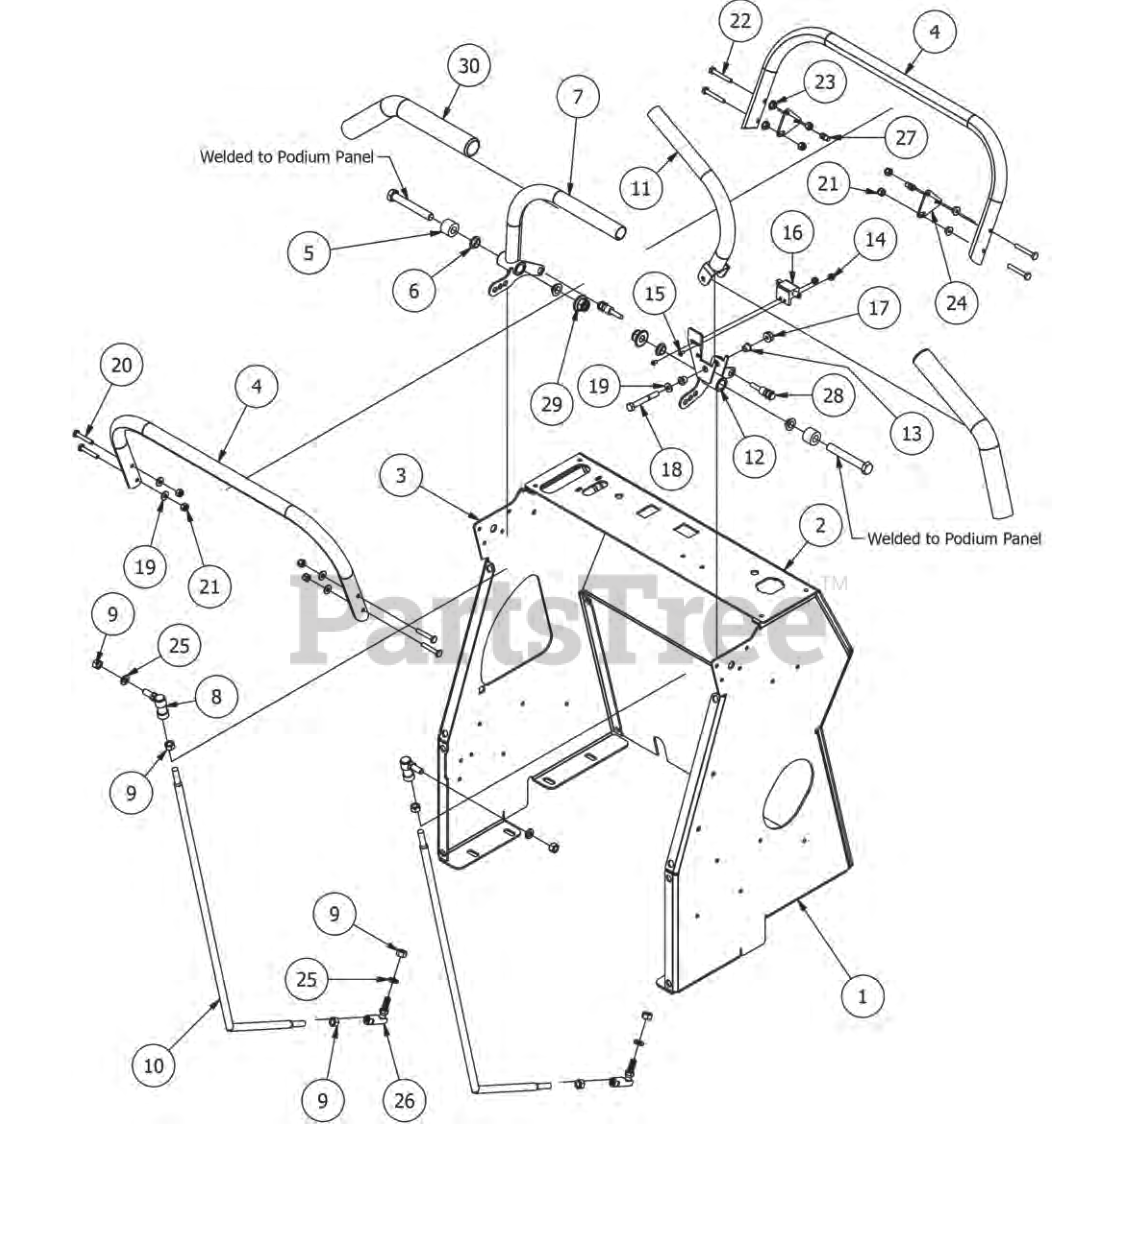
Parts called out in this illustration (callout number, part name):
1	2015 Podium Panel Right
2	2015 Podium Front Panel
3	2015 Podium Panel Left
4	Support Handle Stand Up (Front & Back)
5	Steering Arm Spacer-Stand On
6	Bushing for 2012 Drive Arms
7	Left Steering Handle Assembly
8	3/8-24 Quick Release Ball Joint
9	3/8" Fine Threaded Jam Nut
10	Push Rod Stand On
11	Right Steering Handle Assembly
12	Safety Kill Switch Assembly Bracket
13	Stand On Flange Bushing-Steering Arms
14	#10 Nylock Nut
15	1024 X 5/8" Buttonhead Bolt
16	Safety Switch
17	5/16-18 Nylon Flange Nut
18	5/16" x 2 1/2" Bolt
19	1/4" Flat Washer
20	1/4-20 x 1 1/2" Bolt
21	1/4" Nylock Nut
22	1/4-20x 1-3/4" Hex Bolt
23	1/4-20 Hex Flange Nuts Zinc w/Serrations
24	Neutral Safety Tab
25	3/8" Lock Washer
26	3/8-24 Ball Joint
27	Magnet-Steering Arm-Stand On
28	Safety Switch Harness
29	1/2-13 Nylon Flange Nut-Orange
30	Black Steering Grip
31	1/2 x 3 1/2 Flange Bolt Grade 8
